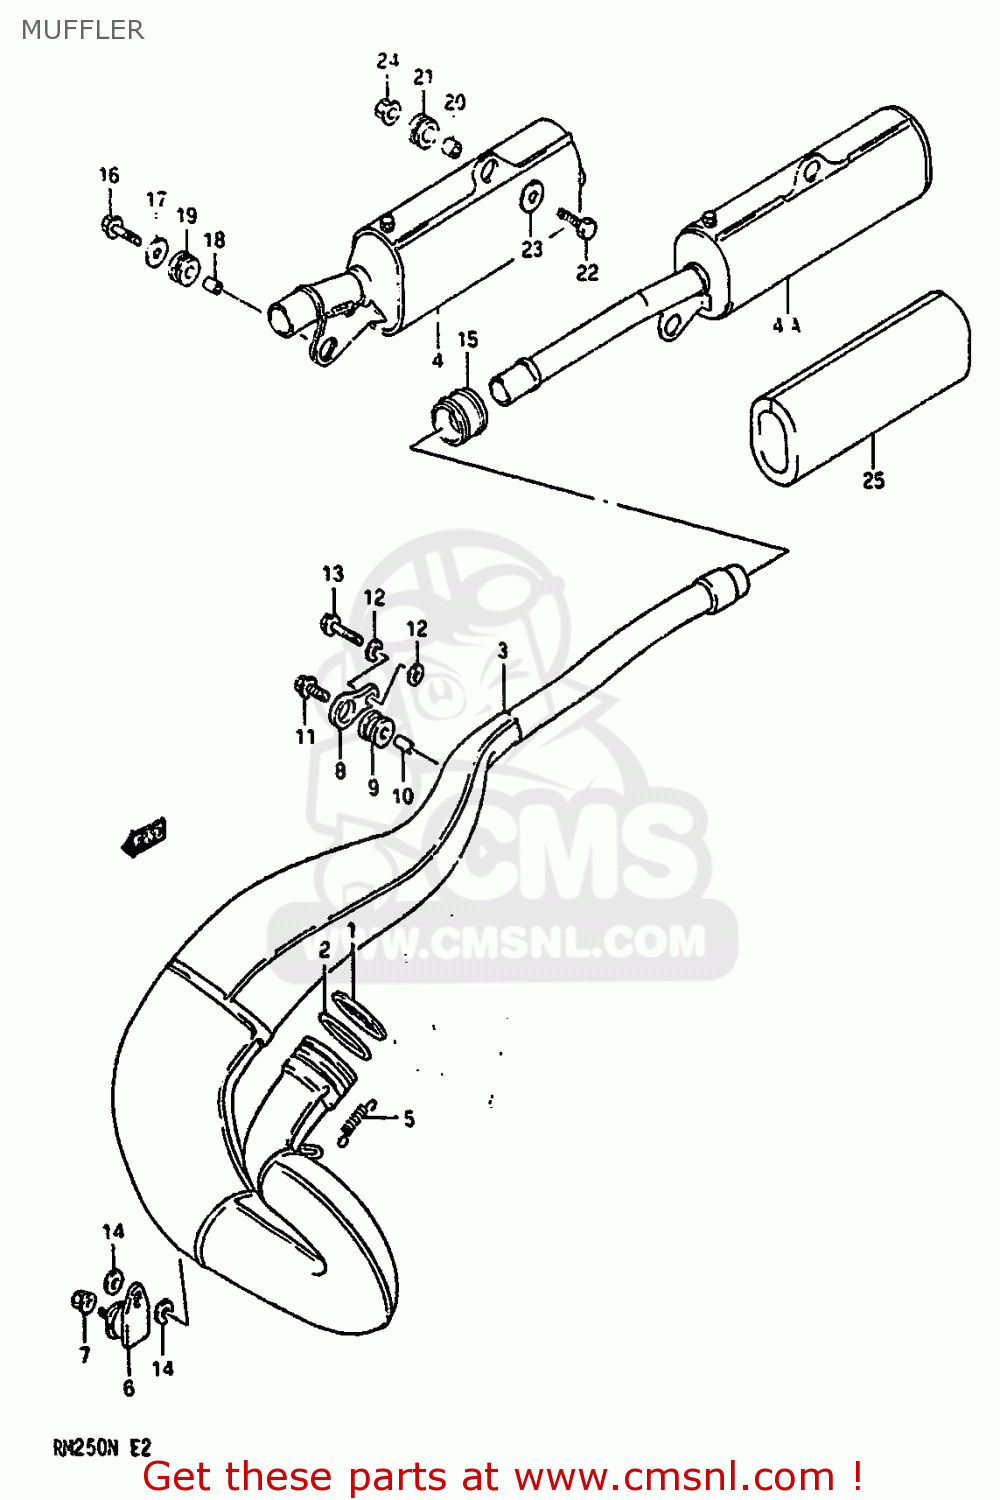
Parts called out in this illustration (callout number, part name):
1	WASHER,EXHAUST PIPE
2	O RING,EX PIPE
3	BODY,MUFFLER,FIRST
4	BODY,MUFFLER 2ND
4A	BODY,MUFFLER
5	SPRING
6	DAMPER,MUFFLER SUPPORT
7	NUT
8	PLATE,MUFFLER MTG
9	CUSHION,MUFFLER
10	SPACER(6.4X9X16)
11	BOLT
12	WASHER (6.5X20X1.2)
13	BOLT
14	WASHER
15	CONNECTOR,MUFFLER
16	BOLT
17	WASHER (6.5X29X1.6)
18	SPACER (6.8X10X9)
19	CUSHION
20	SPACER (8.1X11.5X13)
21	CUSHION
22	BOLT
23	WASHER (8.5X29X1.6)
24	NUT
25	SILENCER,MUFFLER
